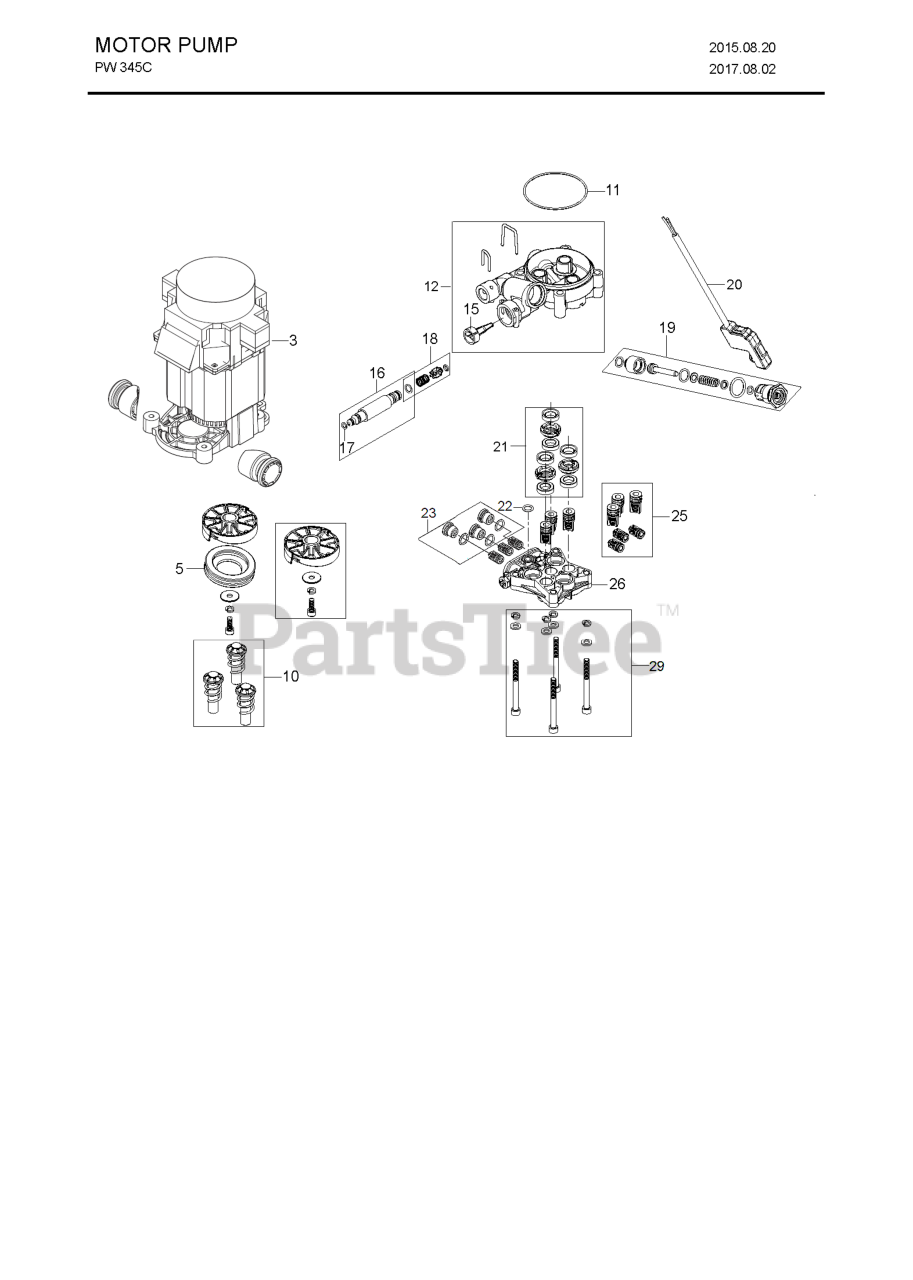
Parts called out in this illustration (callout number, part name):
1	SUSPENSION SEAT
2	BAR.LATCH.SEAT
3	BRACKET.MTG.LATCH
4	BRACKET.SEAT.STAY.ROD
6	ISO-MOUNT INSERT
7	LATCH.ROTARY
8	PLATE.PNT.MTG.SEAT.EDIP
9	ROD.SEAT.STAY
11	NUT.HEX.COUPLING.5/16-18X1-1/8
12	SWITCH.SEAT.DP W/RAMPS
13	HCS 5/16-18 X 5/8 GR 5 ZD
14	SCREW.SHLDER.3/8" DIA X 2.5/16
15	SCREW.HHFS.1/4-20X1.5".GR8.ZY
16	BOLT 5/16C X 3/4" CARRIAGE
17	NUT.FLG.NYLOCK.1/4-20.GR.G.ZY
17	O-RING
18	NUT 3/8 PALNUT RTNG BLK PHOS
19	5/16-18 NYLOC FLANGE NUT
20	WASHER, 3/8 THICK
21	WASHER.13/32 X 1 X 1/2.11GUARD
22	SLW 3/8 STD
23	WASHER.LOCK.HVY.HLCL.SPR.5/16
